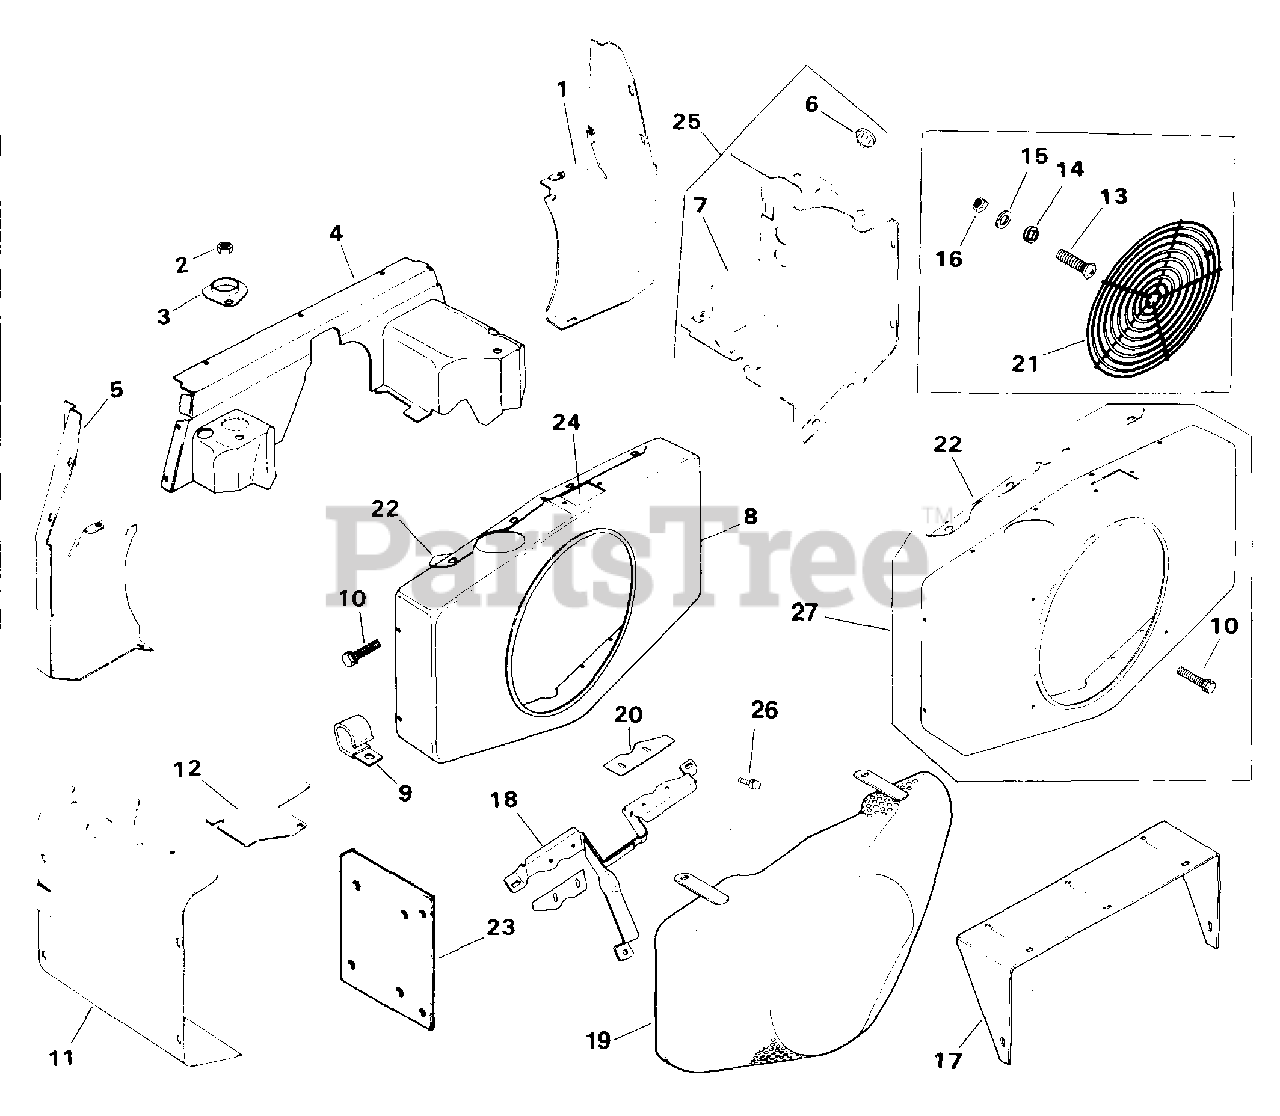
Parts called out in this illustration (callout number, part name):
1	DUCT
1	DUCT, AIR - (#DSC)
2	NUT, 5/16-18 GRADE 5 USE 25 100 22-S
7	BAFFLE - (#DSC)
7	BAFFLE
10	SCREW, WSH HD TAP 1/4-20X7/16" USE 25 086 106-S
12	BAFFLE, FUEL PUMP - (#DSC)
13	SCREW, WSH HD TAP 1/4-20-5/8" - DISCONTINUED
14	WASHER, FLAT 5/16" - DISCONTINUED
22	SUPPORT - (#DSC)
27	KIT, BLOWER HOUSING
